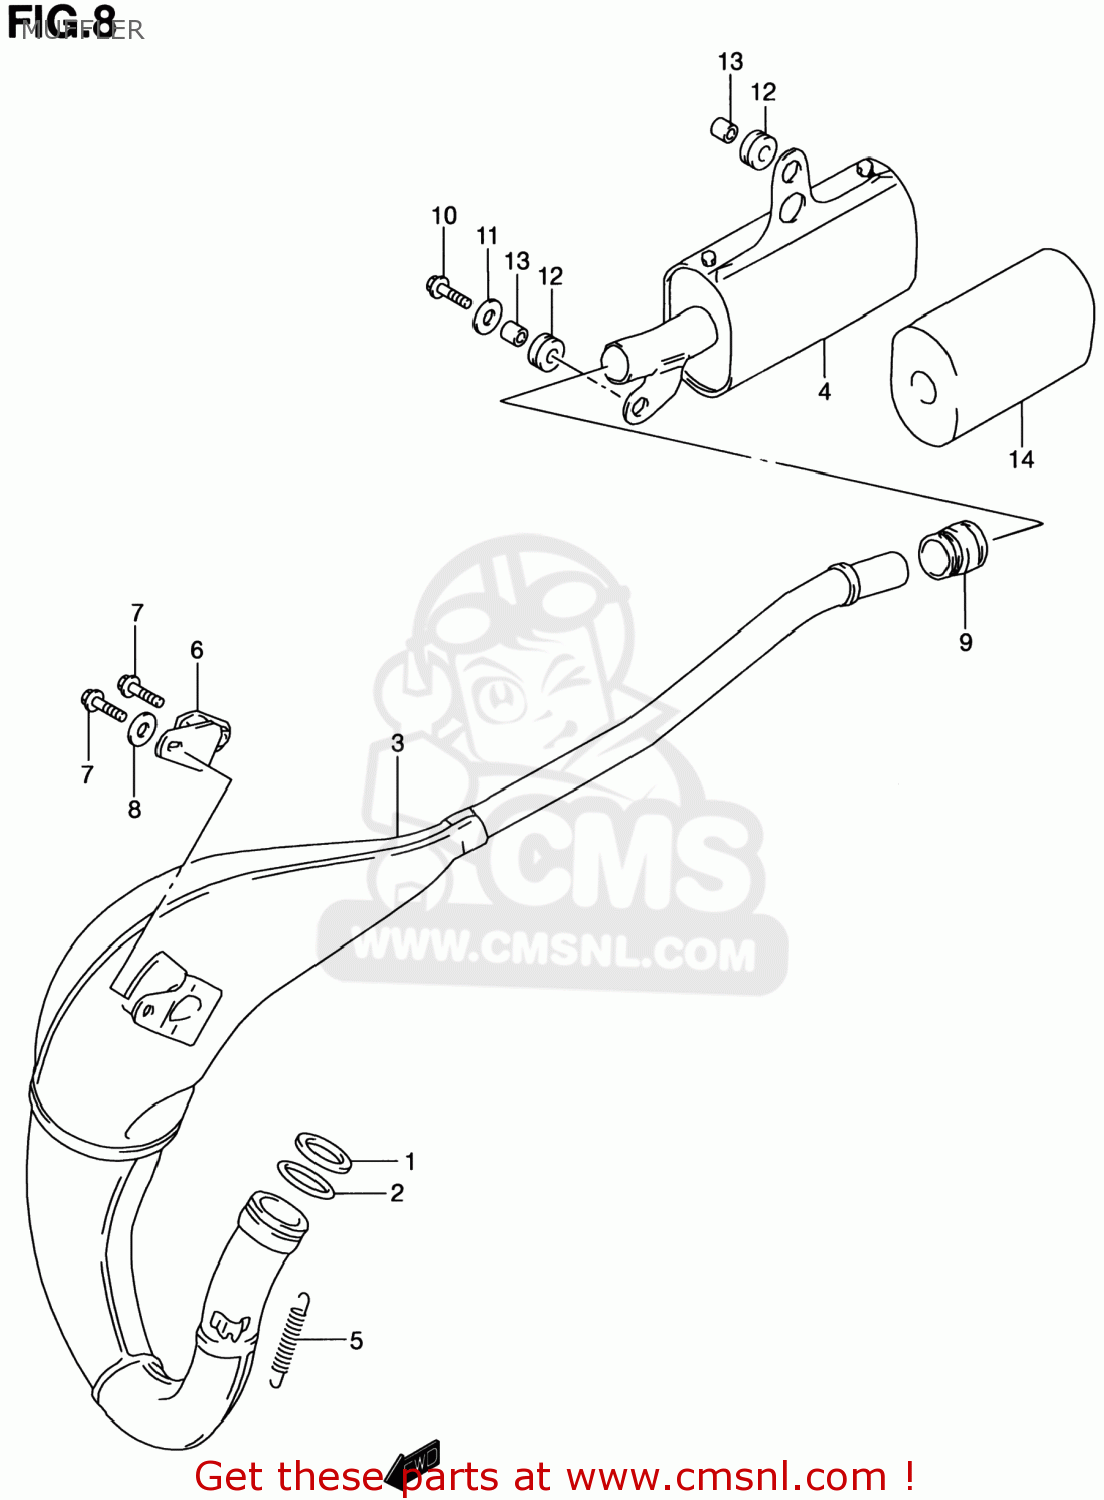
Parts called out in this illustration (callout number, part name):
1	WASHER,EXH FLANGE
2	O RING,EXH FLANGE
3	BODY,MUFFLER 1ST
4	BODY,MUFFLER 2ND
5	SPRING
6	DAMPER,MUFFLER
7	BOLT
8	WASHER(6.5X16X1.2)
9	CONNECTOR,MUFFLER
10	SCREW
11	WASHER(6.5X20X1.2)
12	CUSHION
13	SPACER(6.5X9X8.5)
14	SILENCER,MUFFL
